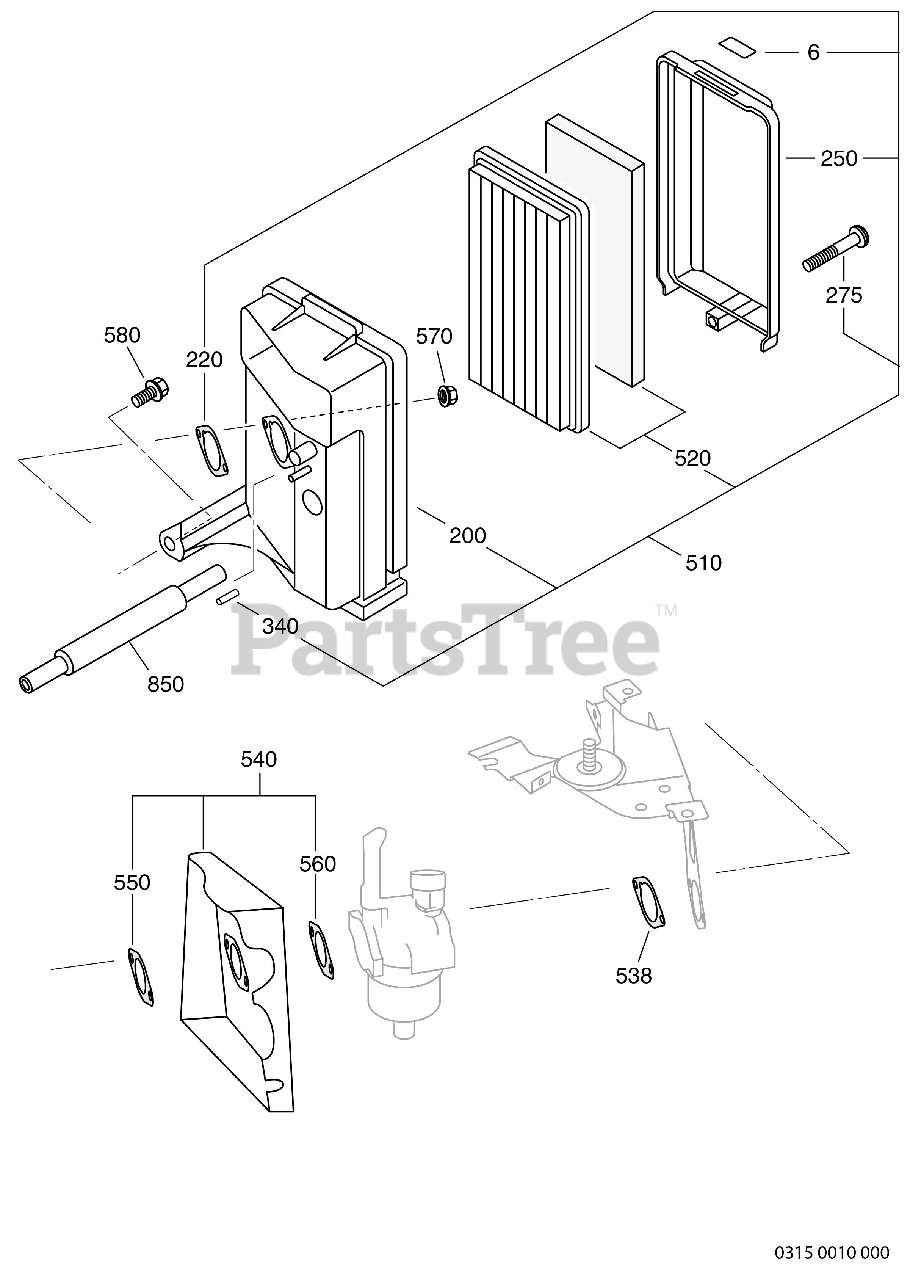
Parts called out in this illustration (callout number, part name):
200	BODY CP
510	AIR CLEANER AY
850	RUBBER PIPE ASSY
